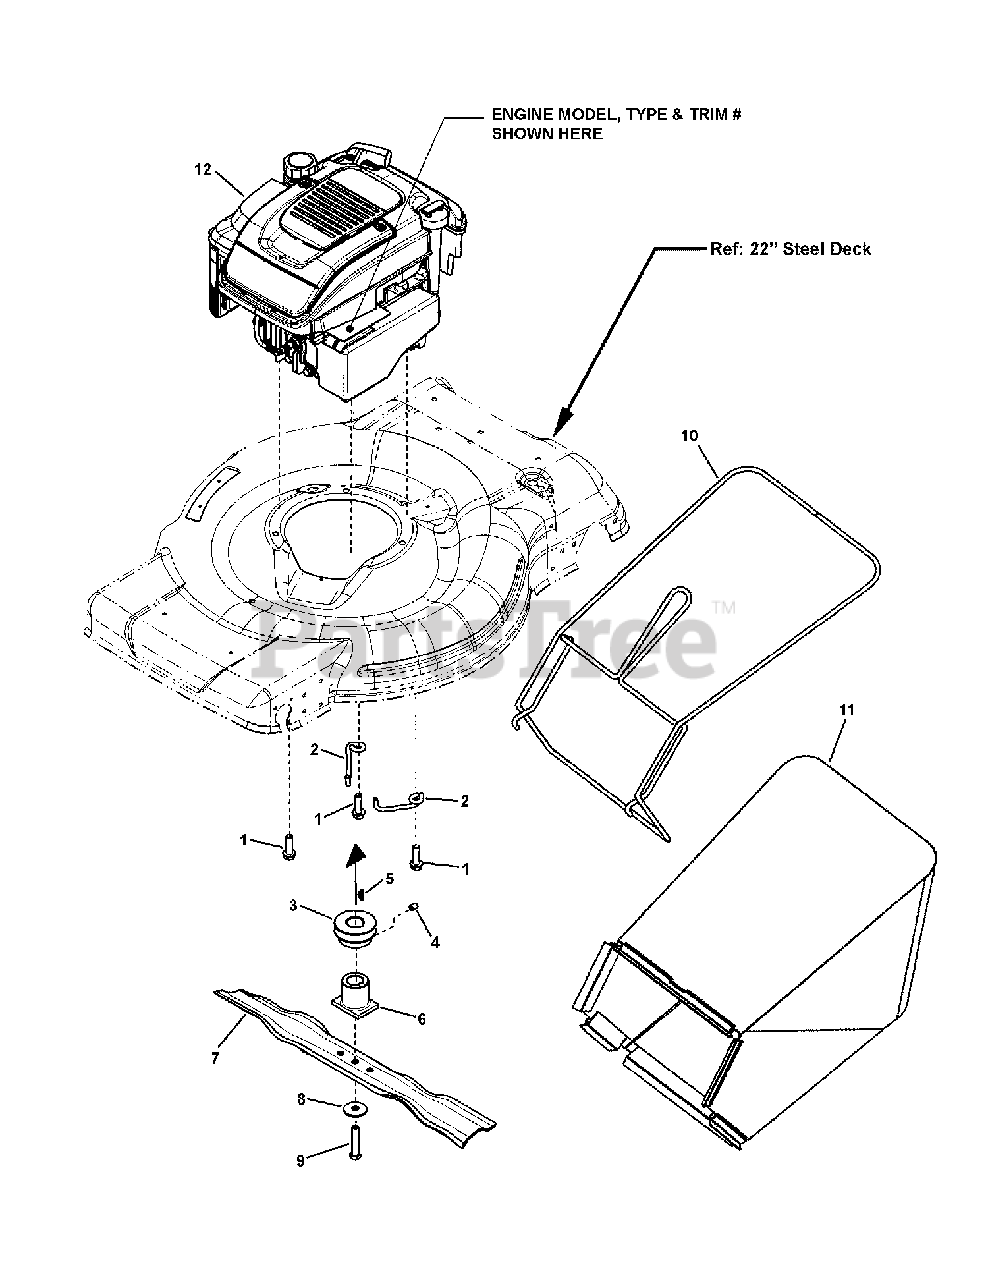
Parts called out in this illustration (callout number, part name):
1	SCREW, 3/8-16 x 1-1/4" Hex Washer Self-Tap
2	BELT GUIDE, Engine, FWD
3	PULLEY, Engine
4	SET SCREW, 5/16-18 x 1/2" Hex Recess
5	KEY, # HP-506 Hi-Pro
6	BLADE HUB, 21" WBM, RD, 2 Position
7	BLADE, Wave, Steel Deck
8	WASHER, Cone 13/32x1-13/32" Dia.
9	SCREW, 3/8-24 x 2" Hex Head Cap, GR 5
10	BAG FRAME, Rear Discharge (weldment)
11	GRASS BAG, 22" Rear Discharge
12	* ENGINE, B&S, 700 Series, B3, X-Spec
12	* ENGINE, B&S, 700 Series, F1, X-Spec
